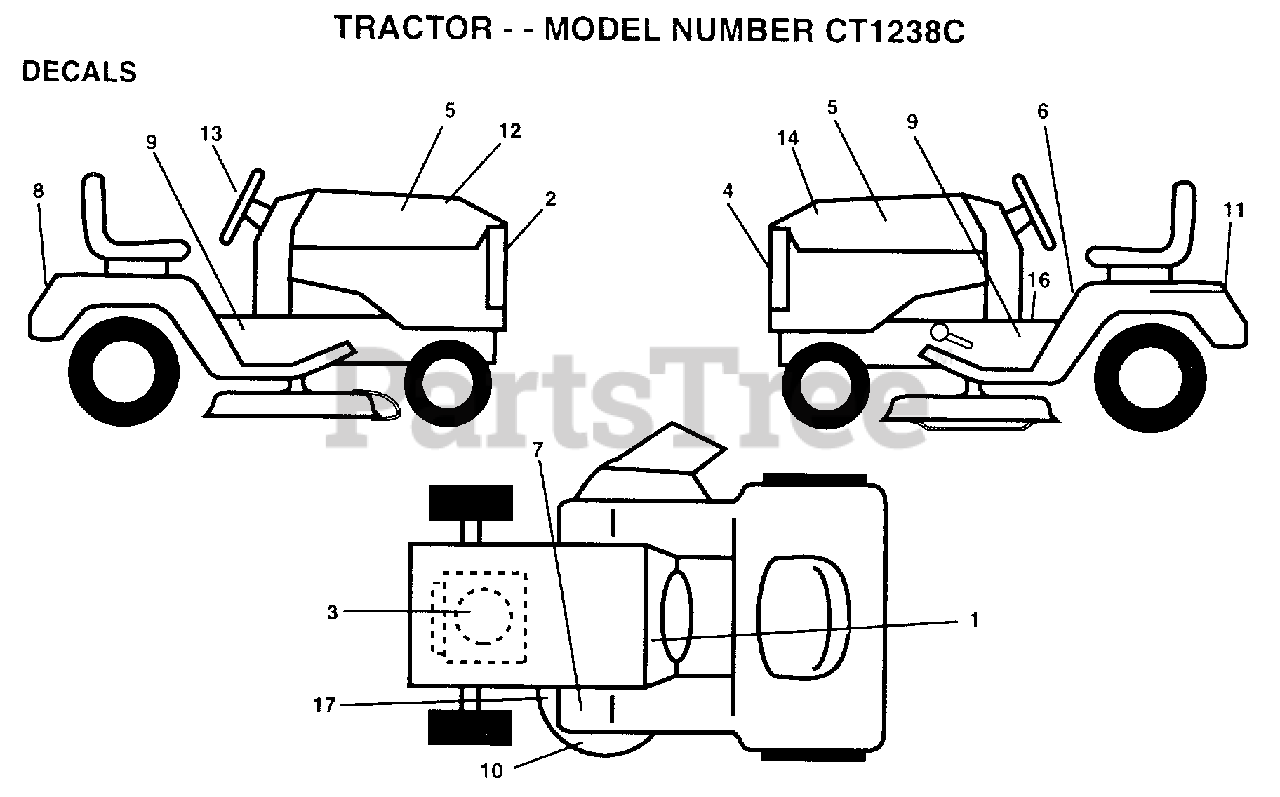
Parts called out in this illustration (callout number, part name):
1	DECAL.DASH.INST.
2	GRILL DECAL
3	DECAL, HP ENGINE
5	DECAL.HOOD.INS.
6	DECAL
8	FENDER DECAL
9	DECAL CHASSIS SPEED DECK
11	DECAL.BTRY.DANGER
12	DECAL HOOD RH RLY
13	"DECAL,STR WHL"
14	DECAL HOOD LH RLY
16	DECAL BRAK PARK
17	DECAL
